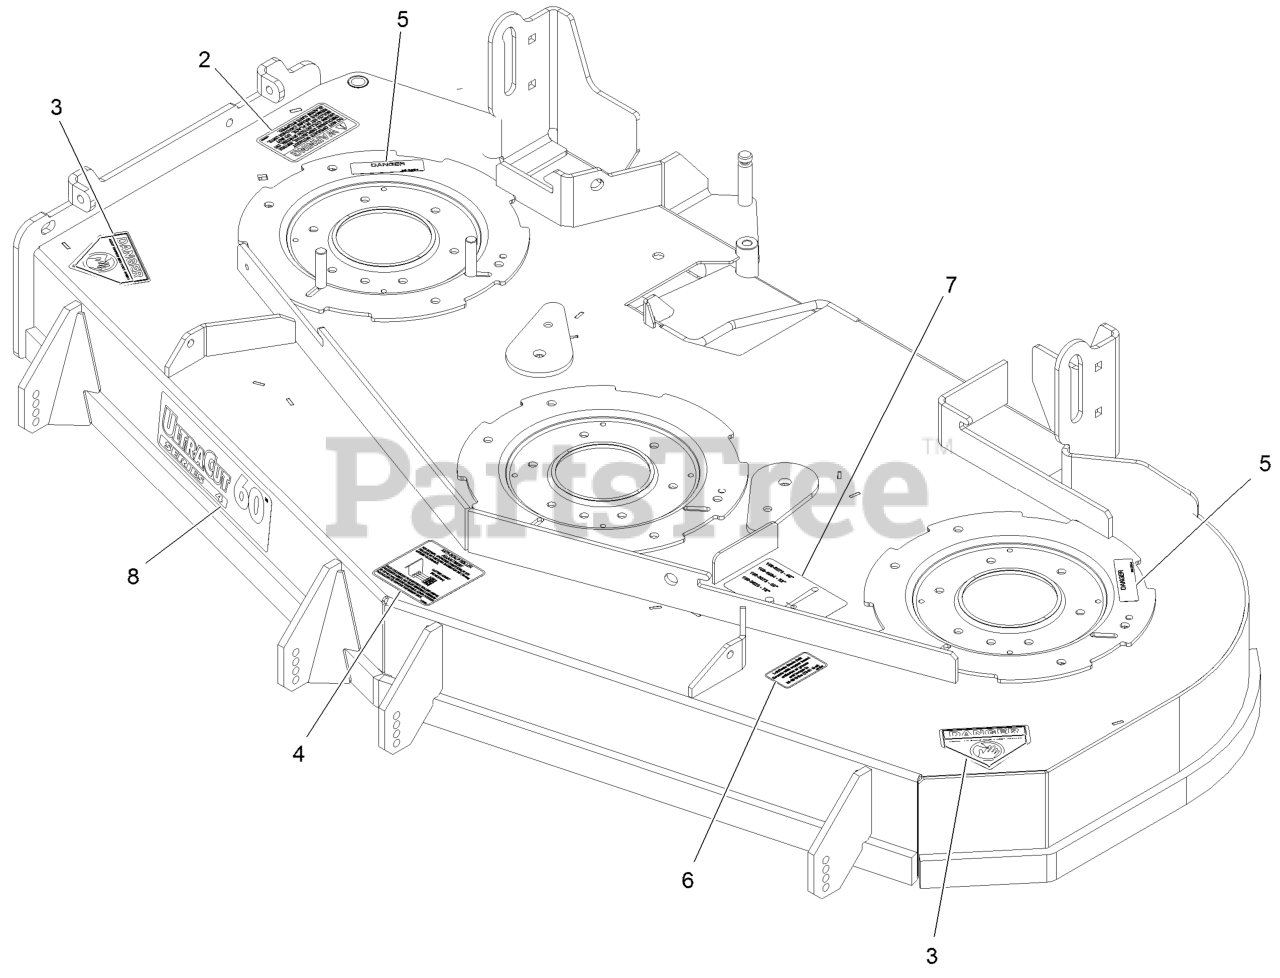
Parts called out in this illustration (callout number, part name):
2	DECAL-WARNING, DISCHARGE
3	DECAL-DANGER
4	DECAL,ANTISCALP
5	DECAL-COVER, MISSING
6	DECAL,BOLT TORQUE
7	DECAL,BELT ROUTING
8	DECAL,ULTRACUT 60 SERIES
